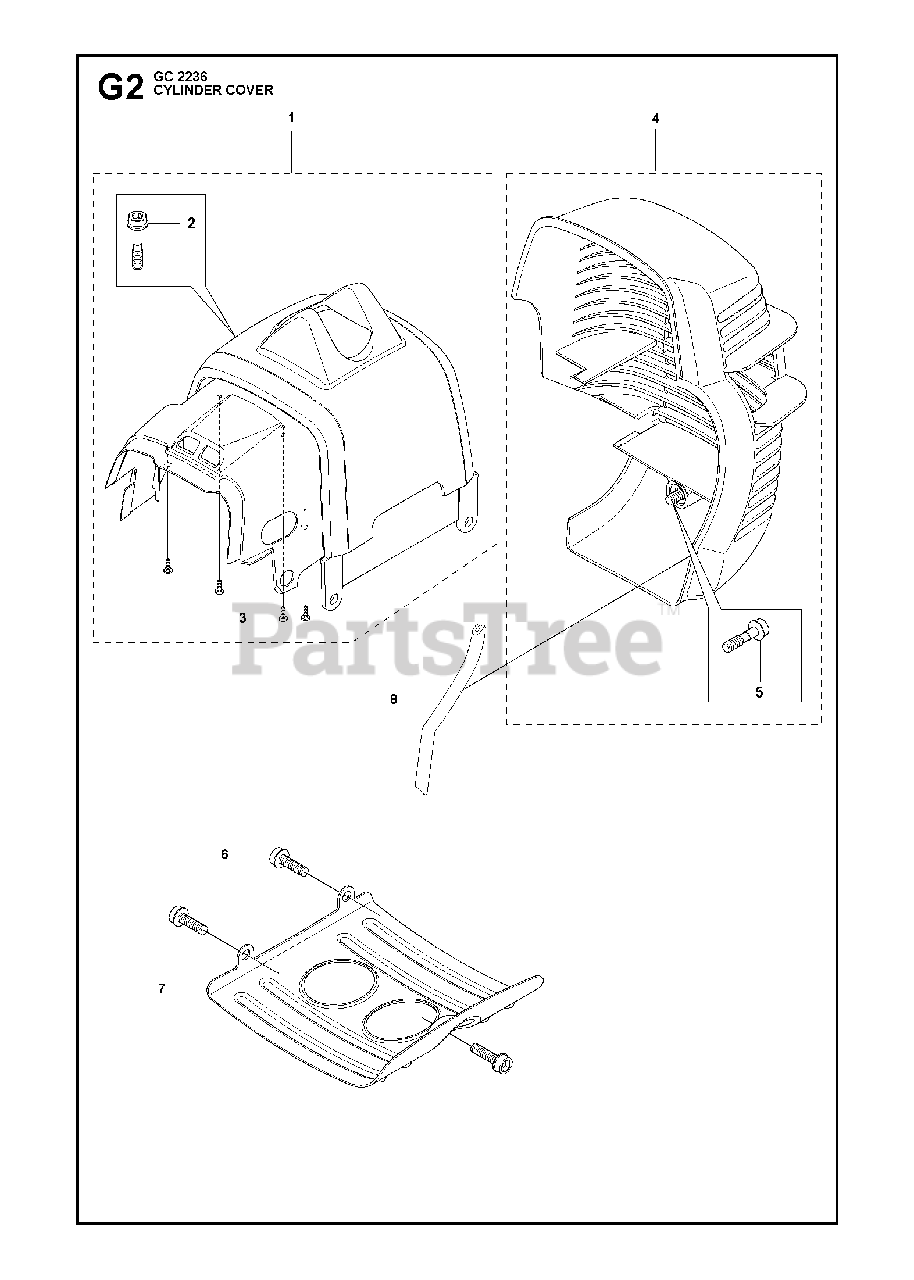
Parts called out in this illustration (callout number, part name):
1	CYLINDER COVER
2	SCREW IHSCFMO
3	SCREW
4	HEAT PROTECTOR
5	HEAT PROTECTOR
